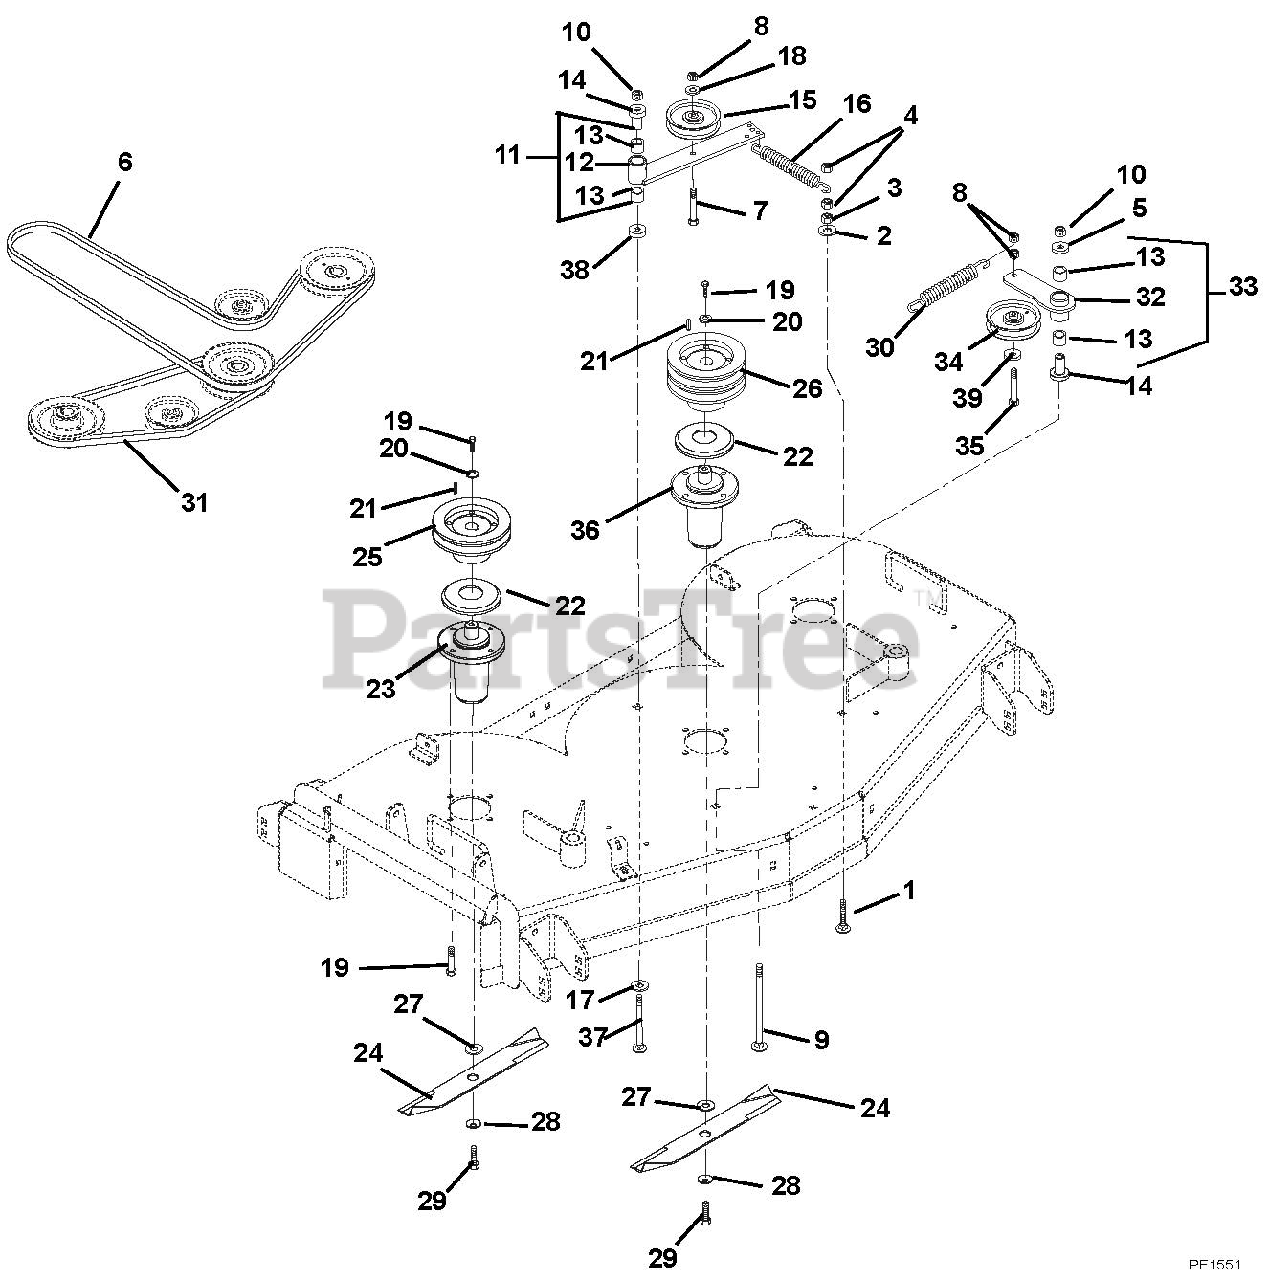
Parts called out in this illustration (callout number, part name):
1	Bolt-Round Head Square Neck .38-16 x 1.50 Grade 5
2	Washer-Locking .38 x .094 Regular
3	Nut-Hex .38-16
4	Nut-Locking-Center .38-16
5	Washer-Flat-Steel .531 x 1.25 x .10
6	V-Belt B-Section 39.38 x .65
6	V-Belt B-Section 42.25 x .65
7	Bolt-Round Head Square Neck .38-16 x 2.75 Grade 5
8	Nut-Locking-Center .38-16
9	Bolt-Round Head Square Neck .50-13 x 3.50 Grade 5
10	Nut-Locking-Center .50-13
11	Assembly, Idler Pivot Arm
12	Weldment, Idler Pivot Arm
13	Bearing, 1.00 x 1.12 x .75
14	Bearing, Pedestal Powdered Metal
15	Idler-Flat 4.00 x .38
16	Spring, Extension
17	Washer-Flat-Steel .755 x 1.375 x .062
18	Washer-Flat-Steel .375 x 1.125 x .065
19	Bolt-Hex .38-16 x 1.00 Grade 8
20	Washer-Flat-Steel .406 x 1.50 x .245
21	Key, Square .25 x .25 x 1.00 RC 40-50
22	Slinger-Dust
23	Assembly, Maintenance Free Spindle
24	Blade- Mower
24	Blade- Mulching
25	Pulley
26	Sheave, Double
27	Washer, Flat .64 x 1.81 x .250
28	Washer-Bellville .63 x 1.625 x .14
29	Bolt-Hex .62-18 x 1.75 Grade 8
30	Spring, Extension
31	V-Belt 5L-Section 49.97 x .672
32	Arm, Idler Pivot
33	Asm, Idler Pivot Arm
34	V-Idler, 4.00 x .38
35	Bolt-Hex .38-16 x 2.25 Grade 5
36	Spindle Assembly
37	Bolt-Round Head Square Neck .50-13 x 3.75
38	Washer-Flat-Steel .515 x 1.625 x .25
39	Washer-Flat-Steel .406 x .812 x .065
